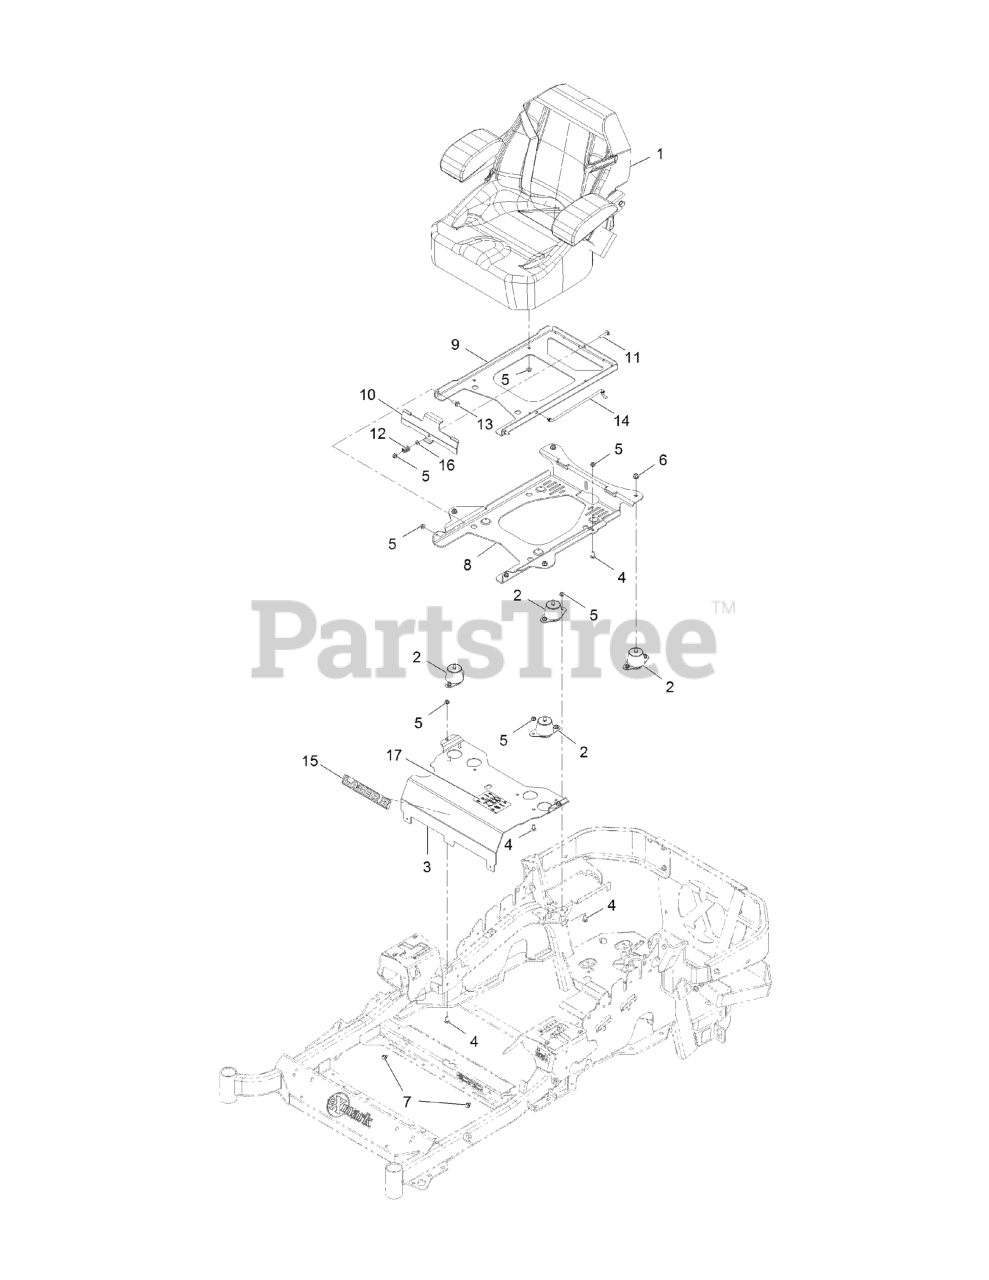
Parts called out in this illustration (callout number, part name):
1	SEAT-EXMARK STANDARD
2	ISOLATOR-SEAT
3	Panel-Front, Seat Mount
4	SCREW-CARR
5	NUT-HF, NI
6	NUT-HF, NI
8	PLATE-TILT, SEAT SUPPORT
9	PLATE-FRAME, SEAT
10	PLATE-LATCH, SEAT
11	BOLT-CARR
12	SPRING-COMPRESSION
13	SCREW-SHOULDER
14	ROD-PROP
15	DECAL, LAZER MODEL
16	WASHER-PLAIN
17	DECAL-SERVICE AID
